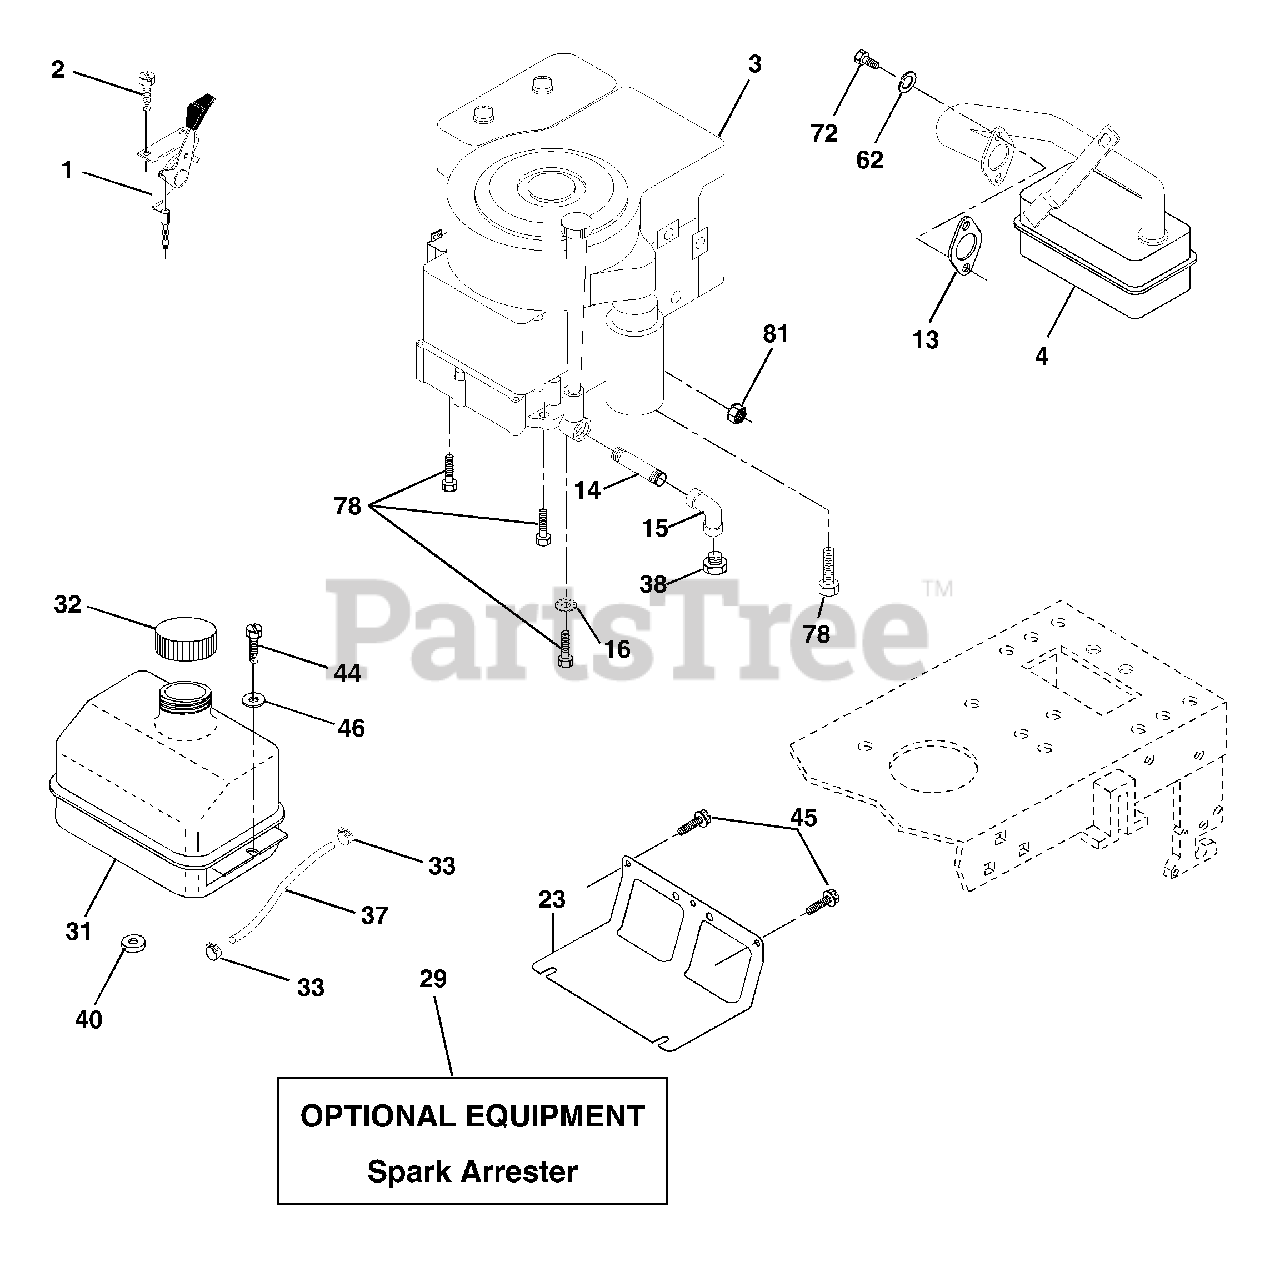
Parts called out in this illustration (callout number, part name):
1	Control Throt /Ch Flag
2	Screw Hex Thd Cut 1/4-20x1/2
4	Muffler Exhaust B&S Lt
13	Gasket 1 313 Id Tin Plated
14	Nipple Pipe 3/8 NPT x 3"
15	Elbow STD 90 Degree 3/8-18 NPT
16	Washer Lock Ext Tooth 3/8
23	Shield Browning/Debris Guard
29	Arrestor Spark
31	Tank Fuel 1 25 Fr
32	Cap Asm Fuel W/sym Vented
33	Clamp Hose Blk
37	Line Fuel 20"
38	Plug Oil Drain
40	Bushing Snap Nyl Blk Fuel Line
44	Screw Hexwsh Thdrol 1/4-20x3/4
45	Screw Hex Wsh Thdrol 3/8-16
46	Washer 9/32 X 7/8 X 16ga
62	Washer Lock Hvy Hlcl Spr 5/16
72	Screw Hexhd Cap 5/16-18x3/4
78	Screw 3/8-16x1-1/4
81	Nut Keps Hex 1/4-20 Unc
